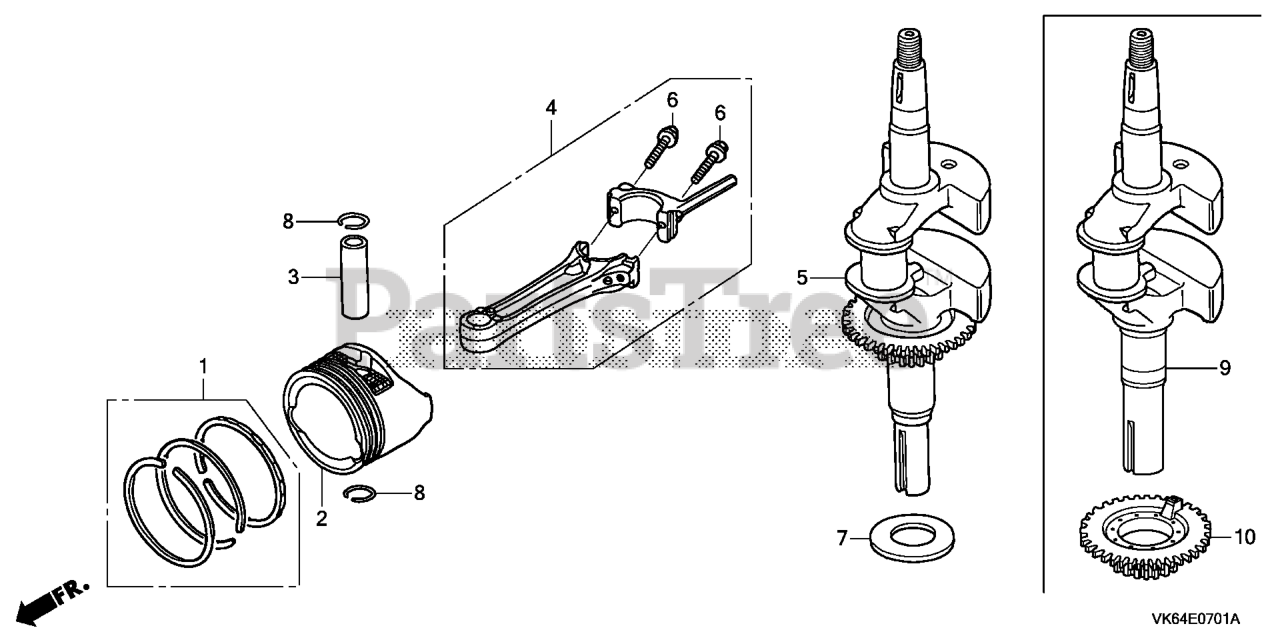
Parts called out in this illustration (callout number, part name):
1	RING SET, PISTON (STD) (TPR)
3	PIN, PISTON
4	ROD ASSY., CONNECTING
4	CONN ROD ASSY.
5	CRANKSHAFT KIT(N4
6	BOLT, CONNECTING ROD
7	WASHER, THRUST
8	CLIP, PISTON PIN (13MM)
9	CRANKSHAFT
10	PULLEY, TIMING BELT DRIVE
